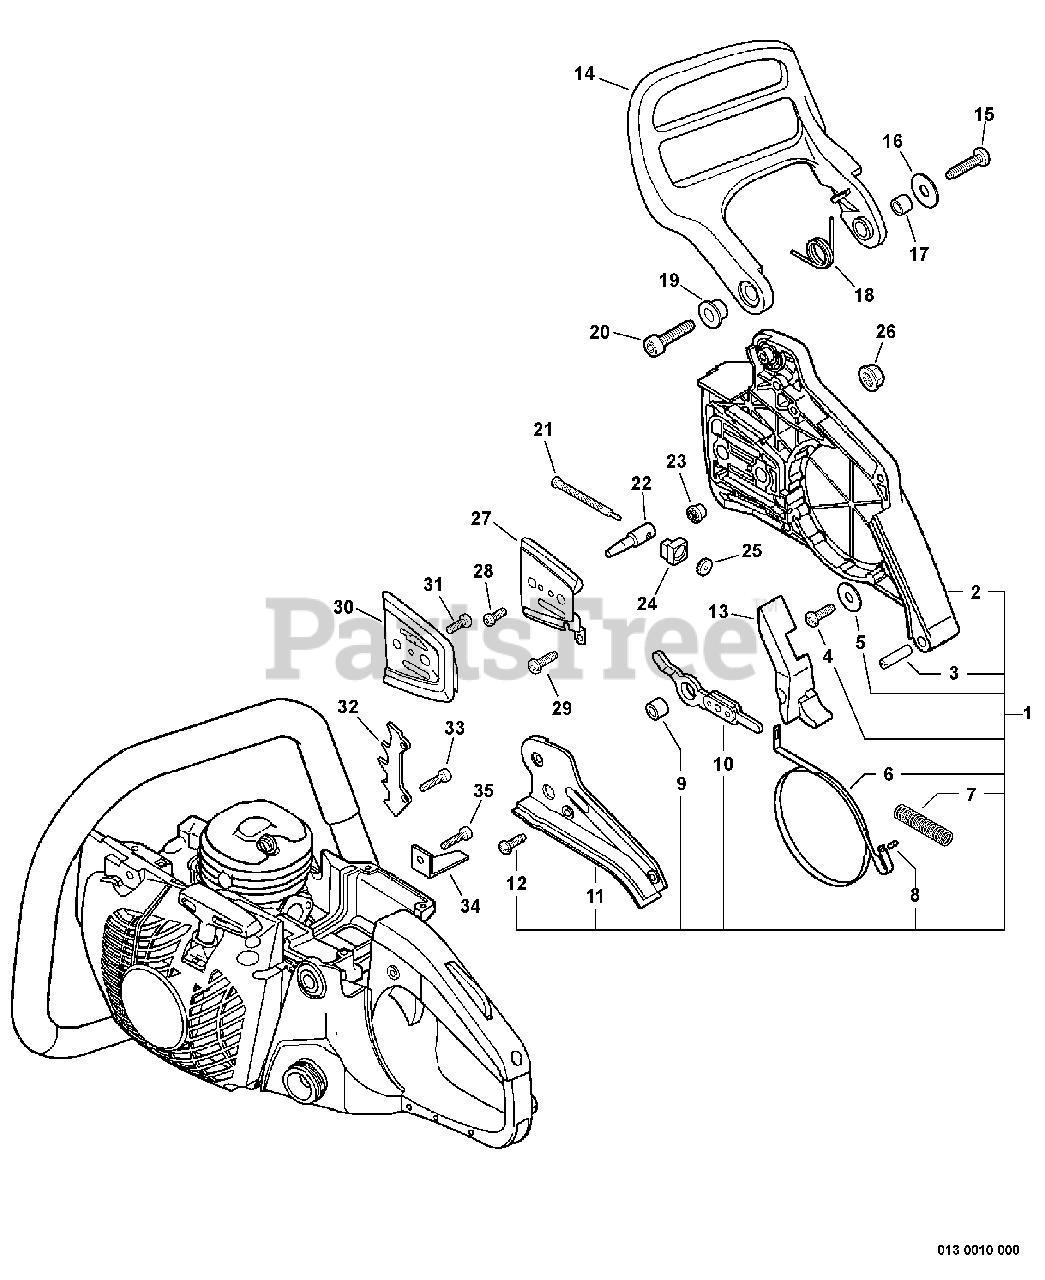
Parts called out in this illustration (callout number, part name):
1	BRAKE ASSY, CHAIN
2	GUARD, SPROCKET
3	PIN, SPRING 6×25
4	SCREW 4×16
6	BAND, BRAKE
7	SPRING, COMPRESSION
8	PIN 3×12
9	SPACER 8×12×9
10	CONNECTOR, BRAKE
11	COVER, BRAKE
12	SCREW 4×12
13	CUSHION
14	LEVER, BRAKE
15	BOLT 4×14
16	WASHER 4.2×16.5×1
17	SPACER 8×12×9
18	SPRING, TORSION
19	COLLAR 10
20	BOLT 5×30
21	SCREW, CHAIN TENSION
22	TENSIONER, CHAIN
23	GEAR, BEVEL
24	COLLAR 8
25	GEAR, BEVEL
26	NUT, FLANGE M8×1.25
27	PLATE, GUIDE - OUTER
28	SCREW 3×6
29	SCREW 4×12
30	PLATE, GUIDE - INNER
31	SCREW 4×6
32	SPIKE, BUMPER
33	BOLT 5×12
34	CHAIN CATCHER
35	BOLT 5×14
